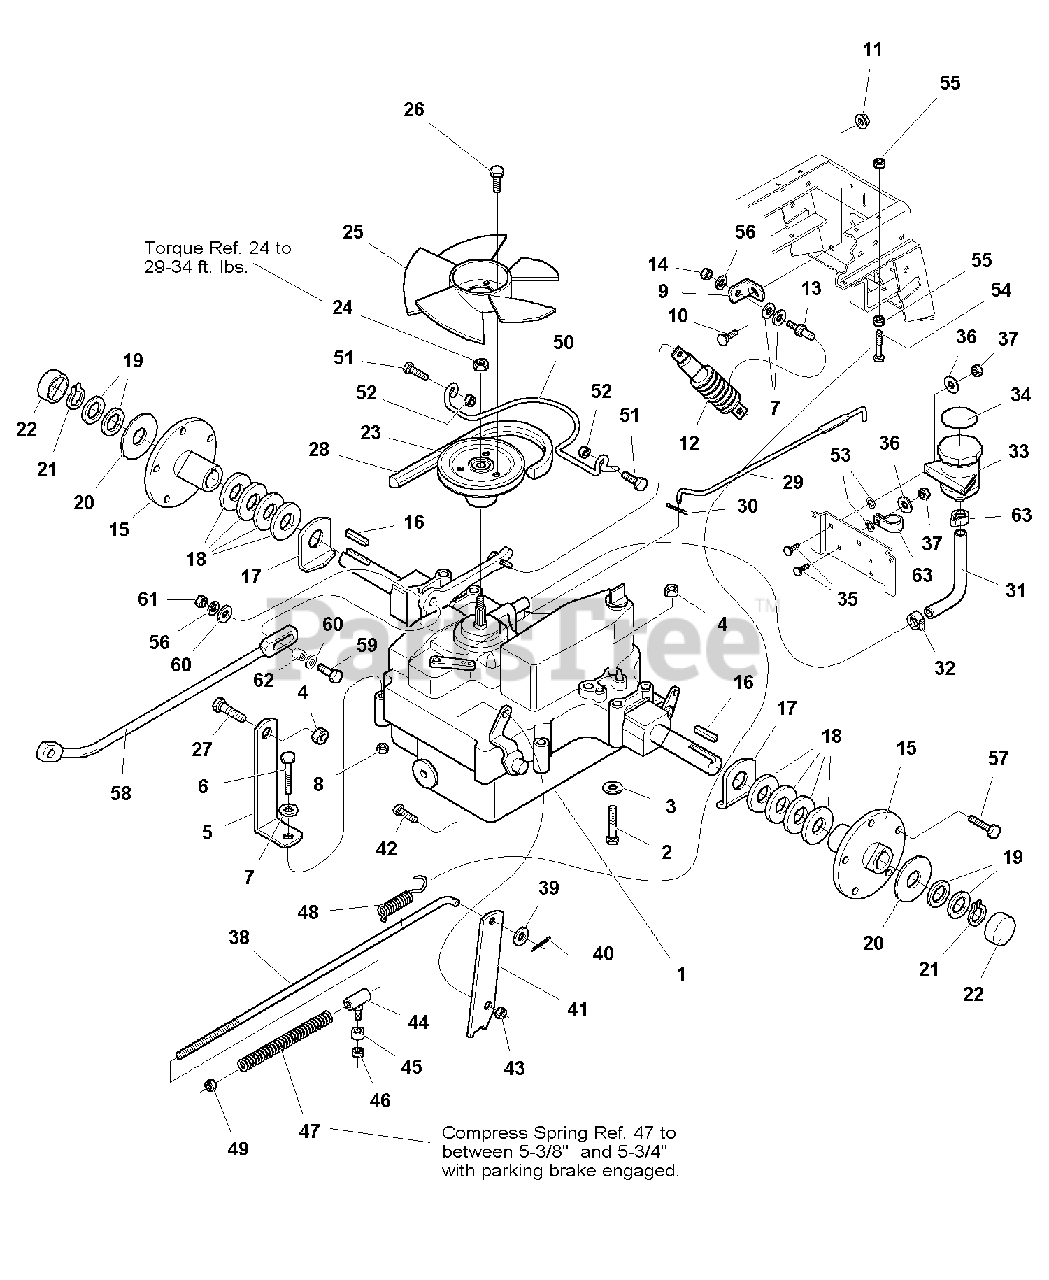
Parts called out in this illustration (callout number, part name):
1	TRANSMISSION, Complete, K71E (with Diff Lock)
1	TRANSMISSION, Complete, K71G
1	TRANSMISSION, Complete, K71J
2	CAPSCREW, Hex Head, 3/8-16 x 4-1/4
3	WASHER, 3/8 (Qty 6 on Diff Lock Units)
4	NUT, Hex Flange, 2-Way Lock, 3/8-16
5	STRAP, Torque
6	CAPSCREW, Hex Head, 5/16-18 x 2-1/2
7	WASHER, 5/16
8	NUT, Hex Whiz Lock, 5/16-18
9	BRACKET, Shock Mount
10	CARRIAGE BOLT, 5/16-18 x 1
11	NUT, Hex Flange Whiz Lock, 5/16-18
12	SHOCK ABSORBER
13	STUD, 5/16-18 x 57/64
14	NUT, Hex, 5/16-18
15	HUB ASSEMBLY, Rear Wheel
16	KEY, Hi-Pro, 1/4
17	WASHER SEAL, Axle
19	WASHER, (1 or 2 as Required)
20	WASHER, Retainer, Hub Cap
21	RING, Retainer
23	PULLEY & HUB ASSEMBLY
24	NUT, Hex Flange Lock, M10 - 1.5
25	FAN ASSEMBLY
26	CAPSCREW, Hex Head, Taptite, 1/4-20 x 1-1/8
27	CAPSCREW, Hex Head, Whiz Lock, 3/8-16 x 1-1/4
29	LEVER, Hydro Release
30	PIN, Cotter, 3/32 x 3/4
31	HOSE, Hydraulic
32	CLAMP, Hose, Worm
33	EXPANSION TANK, Hydraulic
34	DECAL, Explansion Tank Cover
35	CARRIAGE BOLT, 1/4-20 x 3/4
36	WASHER, 1/4
37	NUT, Hex Nylon Lock, 1/4-20
39	WASHER, 5/16
40	PIN, Cotter, 3/32 x 3/4
42	CAPSCREW, Hex Head, 1/2-20 x 1
43	NUT, Hex Center Lock, 1/2-20
44	GUIDE ASSEMBLY, Rod
45	SPACER, 21/64 x 1/2 x 7/32
46	NUT, Hex Head, Whiz Lock, 5/16-18
47	SPRING, Compression
48	SPRING, Extension
49	NUT, Hex Nylon Lock, 5/16-18
50	BELT GUIDE, Wireform
51	CAPSCREW, Hex Head, 5/16-18 X 3/4
52	NUT, Hex Whiz Lock, 5/16-18
53	NUT, Push
54	CAPSCREW, Hex Head, 1/4-20 x 1-1/2
55	NUT, Hex Flange Whiz Lock, 1/4-20
56	WASHER, Lock, 5/16
57	BOLT, Hub, Rear Wheel
59	CARRIAGE BOLT, 5/16-18 x 1-1/4
60	WASHER, 5/16
61	NUT, Hex, 5/16-18
62	SPACER, 21/64 x 9/16 x 5/16
63	CLAMP, Large Hose, 1.0 Dia. (Early Models)
